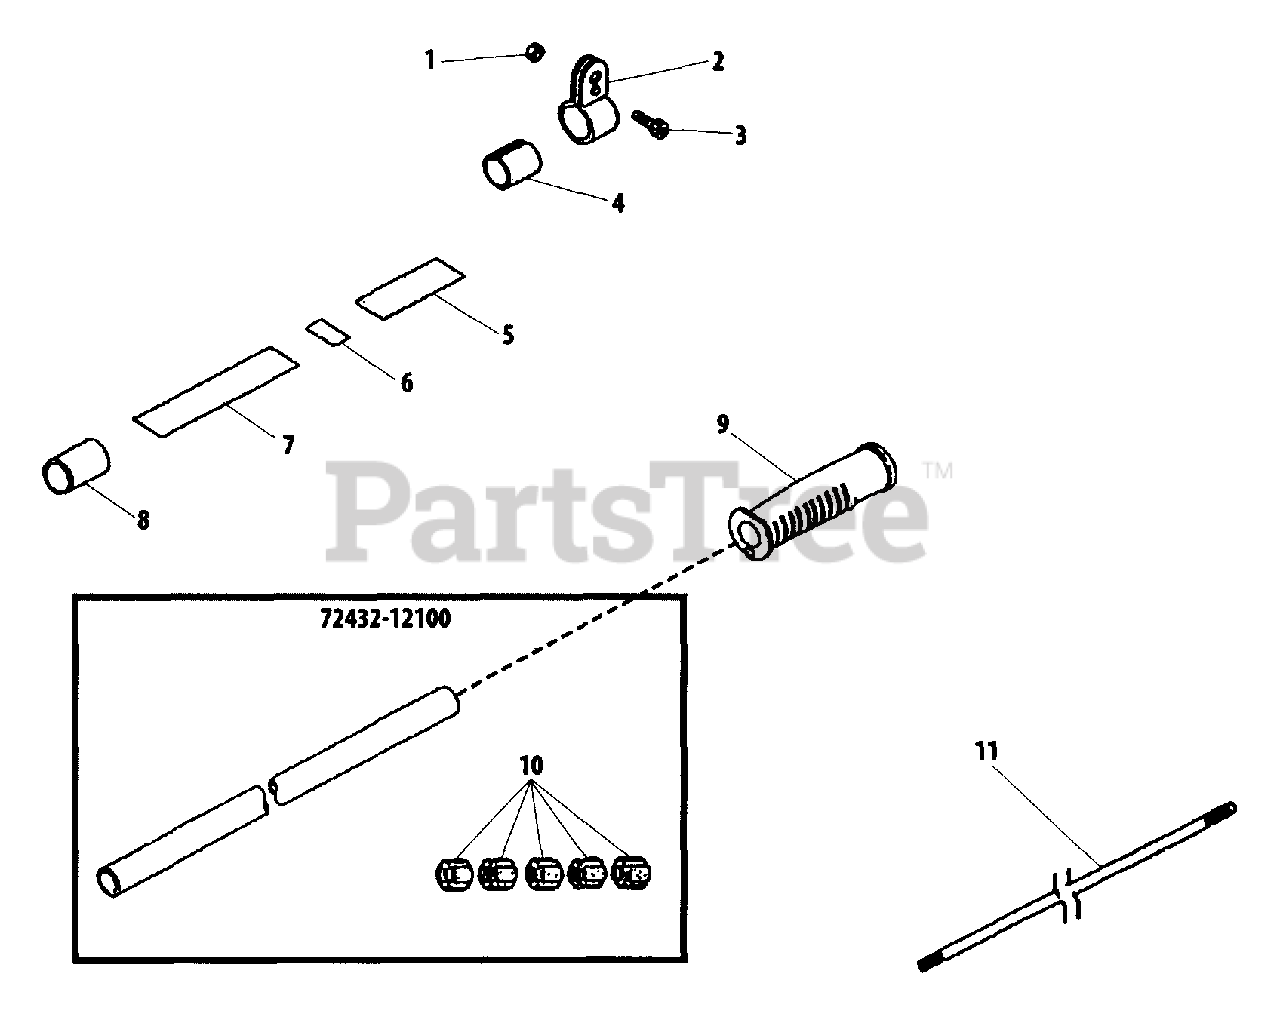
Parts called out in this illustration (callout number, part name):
1	NUT M5
2	HANGER
3	BOLT 5×12
4	SPACER
5	LABEL, CAUTION
6	LABEL, HANDLE
7	LABEL
8	TUBE PROTECTOR
9	GRIP, REAR
10	BUSHING
11	MAINSHAFT
72432-12100	MAIN PIPE ASSY
